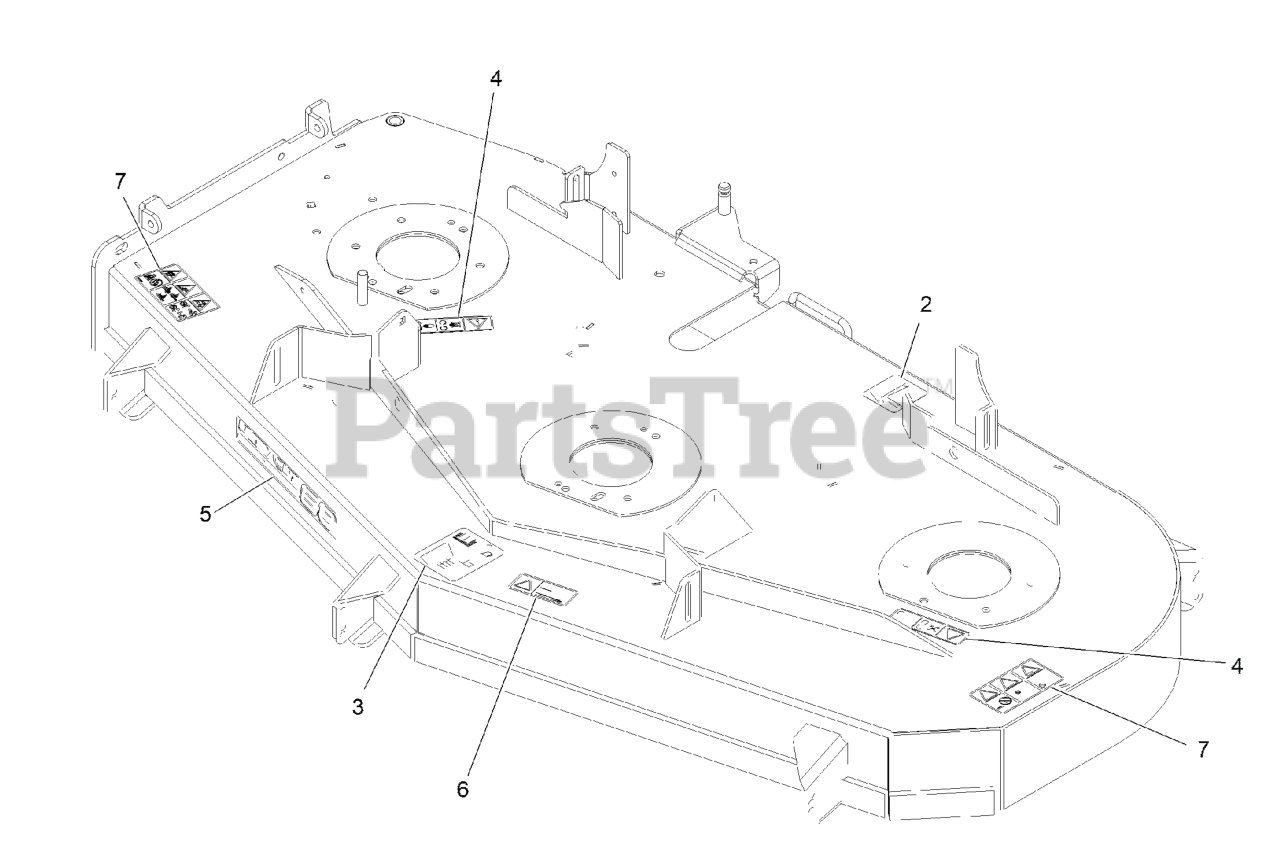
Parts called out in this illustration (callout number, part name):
2	DECAL-ROUTING, BELT
3	DECAL-ROLLER, ANTI-SCALP
4	DECAL-COVER, MISSING
5	DECAL-ULTRACUT 60 SERIES
6	DECAL-BOLT TORQUE
7	DECAL-DANGER THROWN OBJECTS
